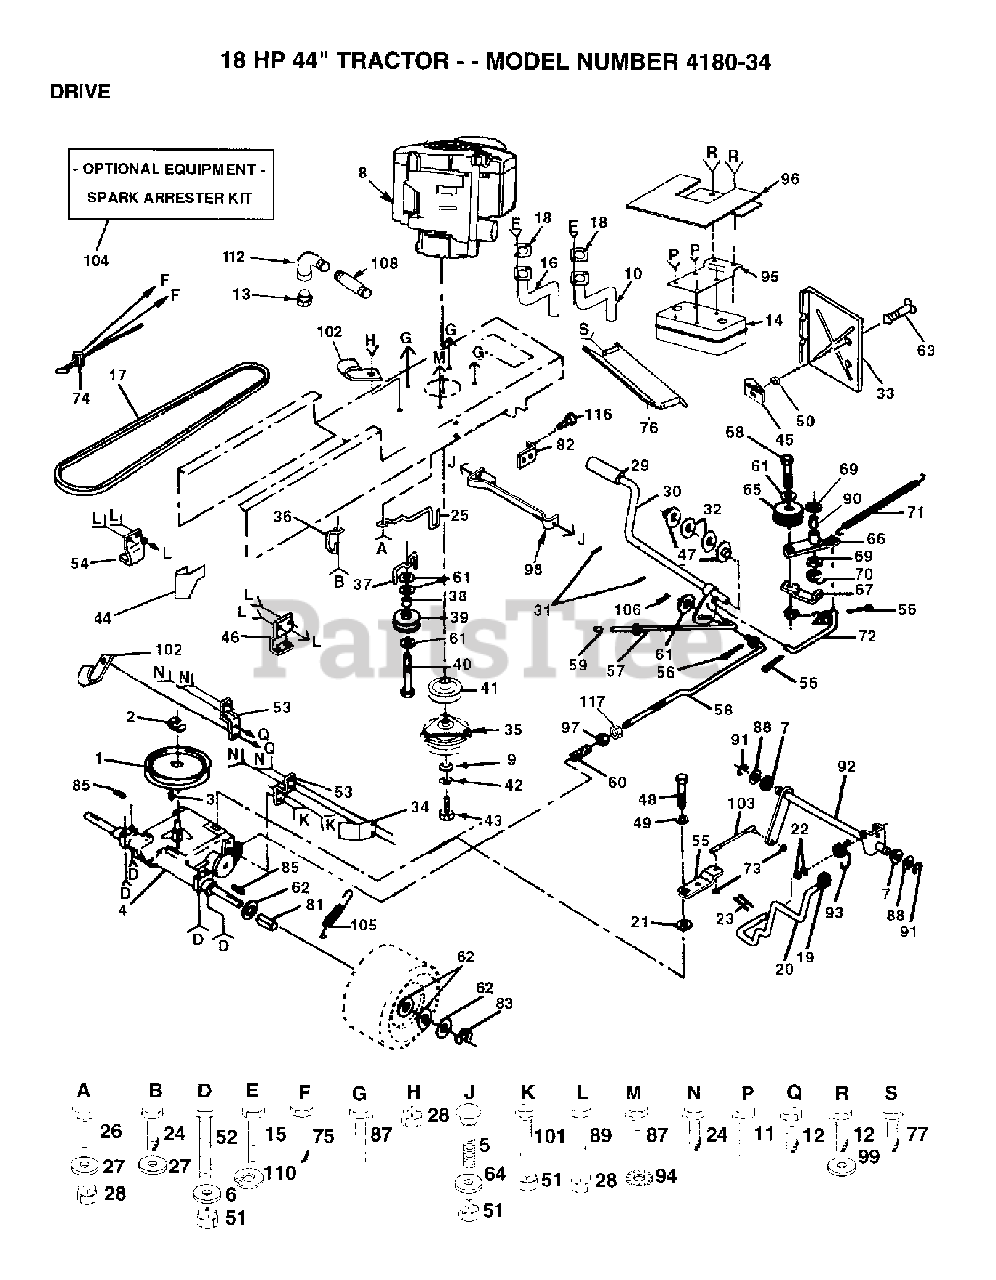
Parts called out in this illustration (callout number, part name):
1	PULLEY TRANSAXLE
3	KEY.WOODRUFF
5	BOLT
7	BUSHING.STEERING.ROD
8	Poulan TBD
11	SCREW ST
12	Screw, Lt
17	BELT.GROUND.DRIVE
18	Poulan TBD
19	KNOB T (1/2-HOLE)
20	ROD SHIFTER
21	WASH-SHFT PLT LT
22	WASHER
23	PIN COTTER
25	KEEPER, BELT
26	BOLT
27	WASHER
28	LOCKNUT
29	PEDAL COVER
31	Drive Pin, 3/16 X 1"
32	WASHER LT
33	SHIELD HEAT HYT
34	KEEPER,BELT RH
36	RETAINER-BELT LT
37	BELT KEEPER LT
38	SPACER T
39	FLAT IDLER PULLEY
41	ENGINE PULLEY
42	LOCKWASHER
43	BOLT
44	KEEPER BELT LH
45	RECEPTACLE LT
46	BRKT TRANS RH
47	BEARING.NYLON
48	BOLT LT
49	WASHER PM
50	RETAINER LT
51	LOCKNUT
53	STRAP TORQUE
54	BRKT TRANS LH
55	ARM,SHIFT
56	COTTER PIN
57	BRAKE PARK ROD
58	ROD BRAKE
59	PLUNGER CAP
60	SPRING,ROD BRAKE
63	STUD 1/4 TURN
64	WASHER T
65	Idler Pulley
67	RETAIN BELT
68	Hex Bolt
69	WASHER LT
70	KLIP RING
71	SPRING, RETURN LT
73	NUT 1/4-28
74	DECK W/DECALS 72" HUS
81	SPACER HYT
82	BRACKET LT
83	E RING HYT
88	WASHER D
90	BEARING LT (2 2)
91	KLIP RING
92	SHAFT,SHIFTER
93	SPRING,TORSION
94	LOCKWASHER
96	HEAT SHIELD
97	NUT
98	BRACKET ASM MTG
99	WASHER
101	BOLT.HEX.3/8-16X2.5".FINISHED
102	CLIP T
104	SPARK ARREST
105	SPRING T
106	RETAINER M
108	NIPPLE, PIPE 3/8NPT X 4-1/2
110	LOCKWASHER
112	ELBOW
117	NUT
